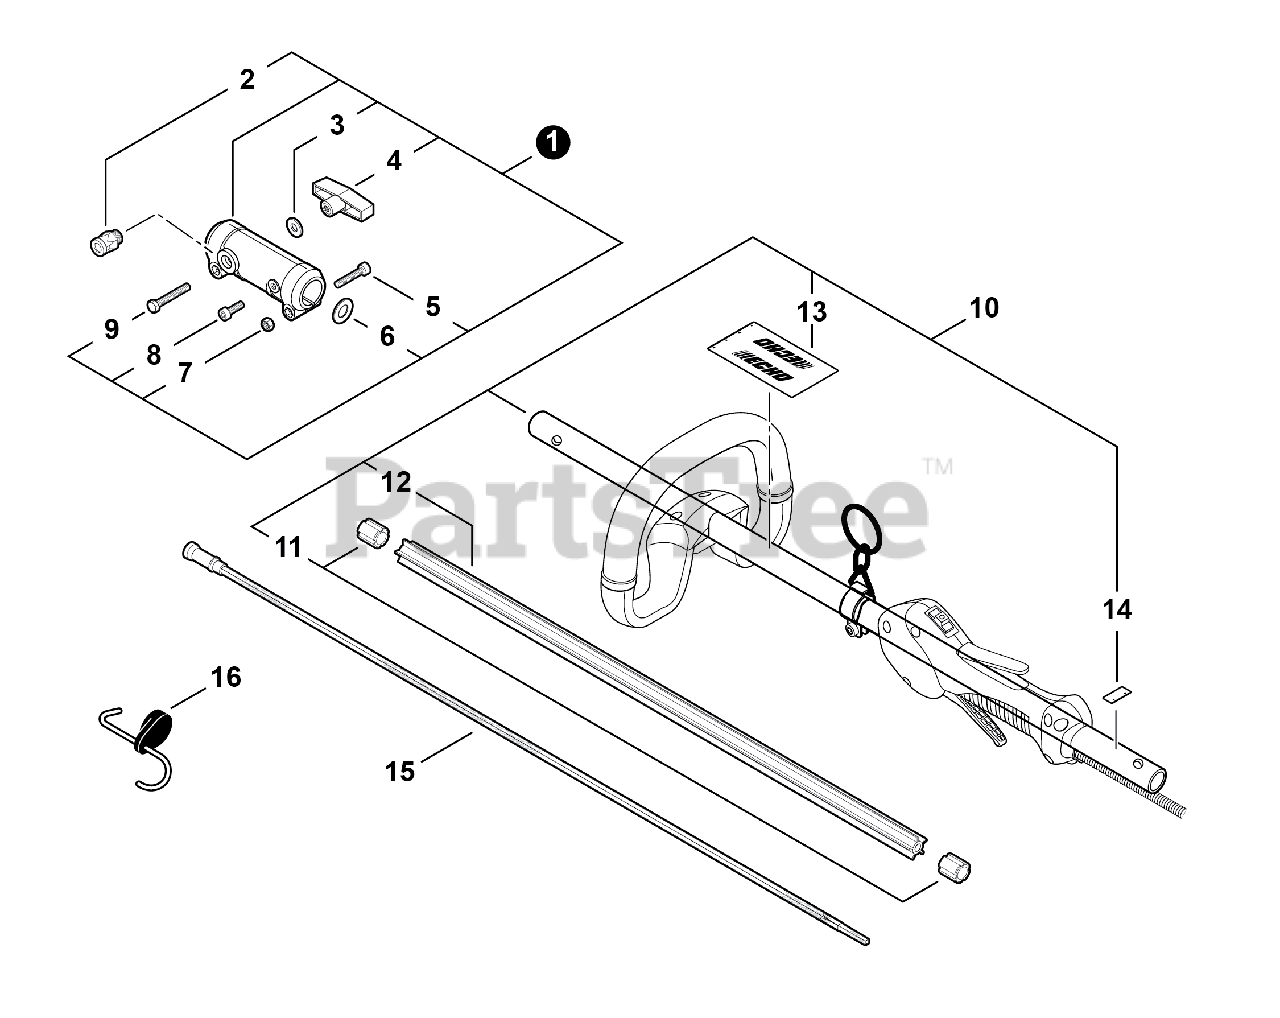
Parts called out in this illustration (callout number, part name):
1	COUPLER ASY
2	LATCH ASY
3	WASHER - 6
4	WINGNUT
5	SCREW - 6X25
6	WASHER - 18
8	SCREW - 5X10
9	BOLT - 6X40
10	MAIN PIPE ASY
12	LINER - FLEXIBLE
13	LABEL - HANDLE LOCATION
14	LABEL - ALIGNMENT
15	DRIVESHAFT - FLEXIBLE
16	ATTACHMENT HANGER
